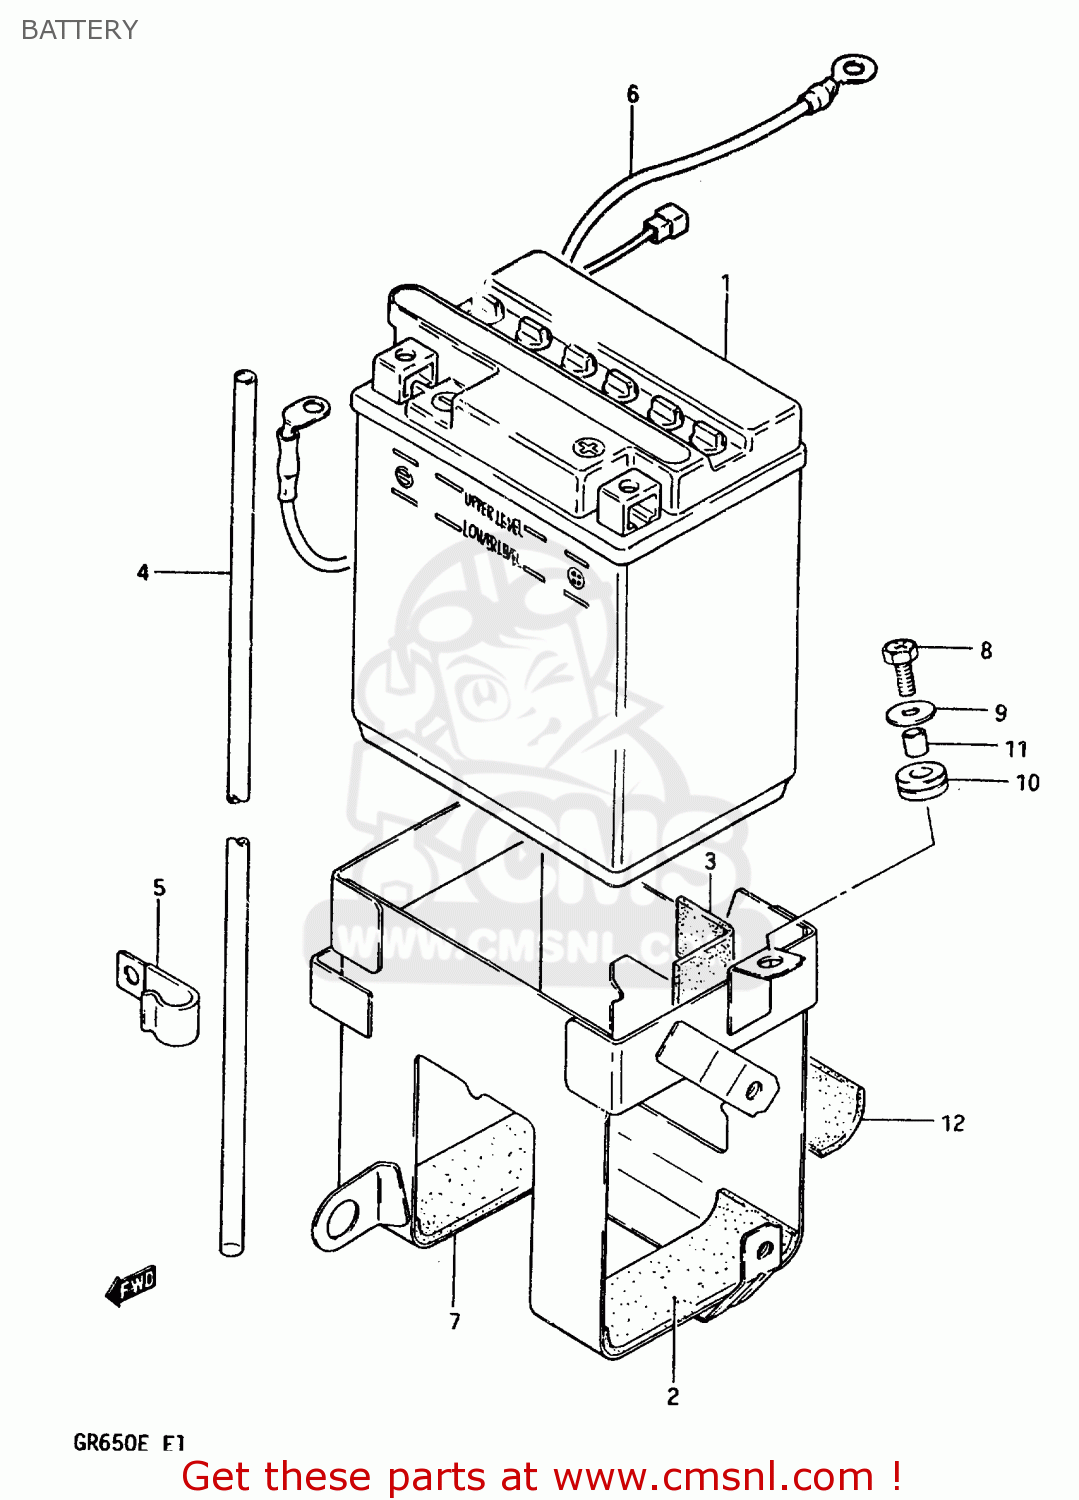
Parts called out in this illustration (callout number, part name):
1	BATTERY ASSY (12V)
2	PROTECTOR(170X95X3.0)
3	PROTECTOR,20X9
4	HOSE,BATTERY EXHAUST
5	CLAMP
6	WIRE,STARTER MOTOR LEAD
7	HOLDER,BATTERY
8	SCREW
9	WASHER
10	CUSHION
11	SPACER(6.1X9X7.5)
12	CUSHION,BATTERY HOLDER
